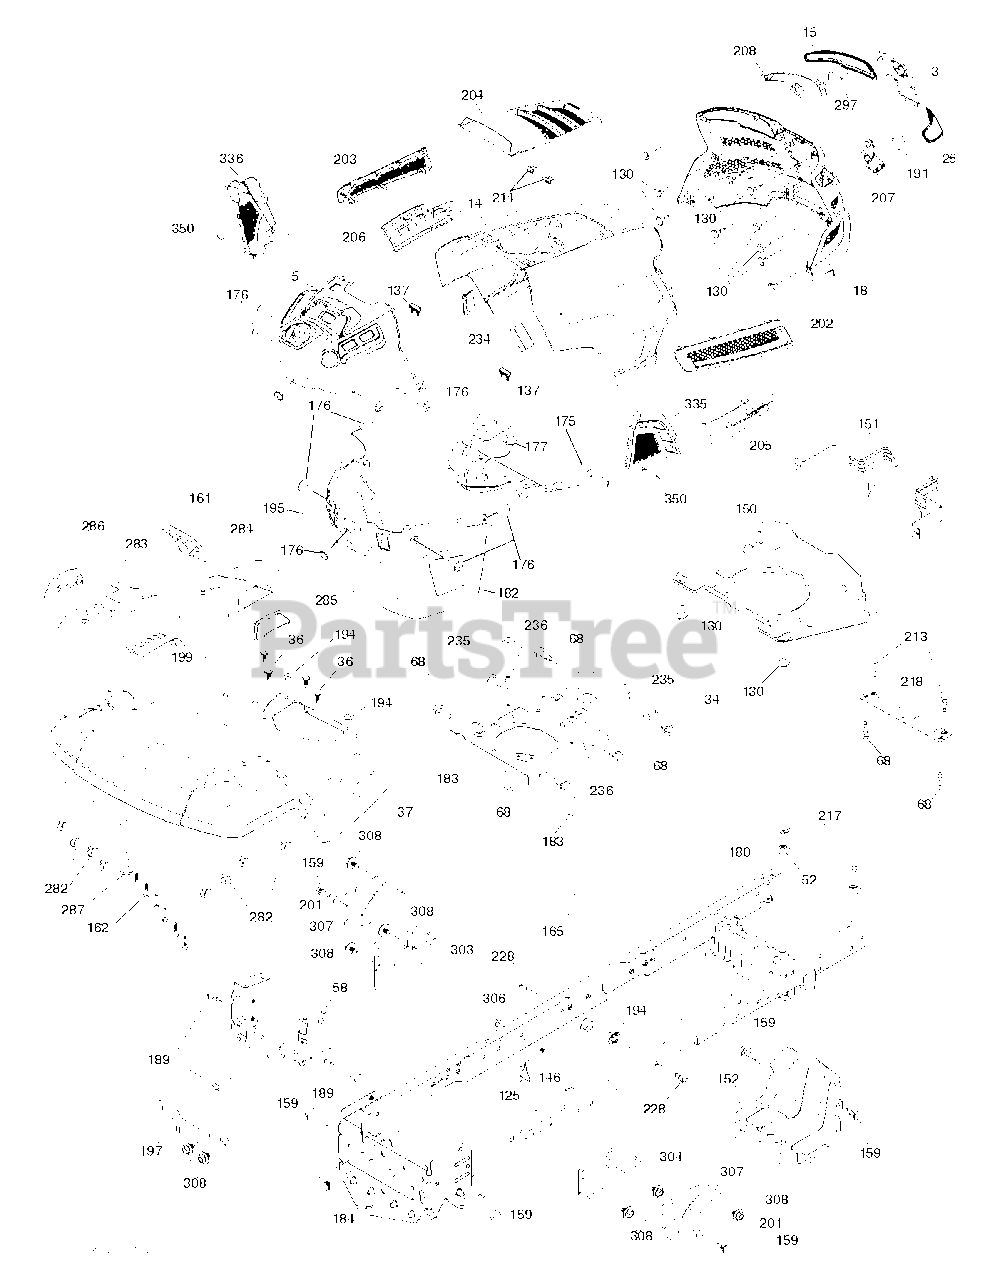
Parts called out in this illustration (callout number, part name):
3	APPLIQUE.SUBASM.GT.HUSQ.II
5	DASH.HUSQ2.SM.E.RS.HR.CHG 498
14	HOOD.ASM.HUSQVARNA.GT.TEX.ORAN
15	LENS.HEADLIGHT.LH.GTII.2011
18	GRILLE.SUBSTRATE.2011.
25	LENS.HEADLIGHT.RH.GTII.2011
34	PLATE.ENGINE.WELDED.CHASSIS
36	SCREW 5/16"
37	FENDER.TLT.FS.W/CPH.W/FW.668
52	LOCKNUT
58	DRAWBAR UPPER 2PC SMALL FENDER
68	SCREW LT
125	CLIP.FUEL.LINE
130	SCREW.#10 X 0.750.BOS
137	BUMPER DASH
146	BOLT.RDHD.SHT.SQNK.3/8-16X5/8
150	AIR.DUCT.GTV.BLACK
151	BRACKET.PIVOT.HOOD.GT.HUSQ.II
152	SHIELD.BROWNING.PNT.GT.V2
159	SCREW, 3/8-16X3/4
161	WINDOW.FUEL.LT.TEX.GREY
162	SCREW.HI-LO.CONSOLE
165	SUPPORT.TANK.REAR.W/TEX
175	PLATE.CROSSMEMBER.HUSQ
176	SCREW.#10-24X5/8.RN.QU
177	BUSHING, STEERING
180	CHASS.WLDMNT.TLT.12GA/2PC.20"
182	DASH LOWER.HUSQ.PRED NO CRUISE
183	BOLT.5/16-18X1-1/4 FULL THD
184	PLUG.DEMO.625
189	SCREW
191	INSERT.REFLECTIVE.RH.HUSQ.GTII
194	NUT LOCK HEX FLANGE 5/16-18
195	PLUG.HOLE.DASH.LOWER.12V.BLK
197	SHIELD.DRWBAR.LT.RTANK.431
199	PLATE.DECK.LIFT.HUSQ.LT
201	WASHER
202	VENT.SIDE.RH.GT.HUSQ.II.
203	VENT.SIDE.LH.GT.HUSQ.II.498
204	VENT.TOP.HUSQ.GT2
205	SIDE.TRIM.RH.GT.HUSQ.II
206	SIDE.TRIM.LH.GT.HUSQ.II.GRAY
207	BEZEL LIGHT.RH.GT.II.MYLAR
208	BEZEL LIGHT.LH.GT.II.MYLAR
213	BOLT
214	CLIP.RETAINER.TINNER.
217	ROD.PIVOT.HOOD
218	X-PIECE.HOOD.STOP.NON/
228	STUD.FASTNER.W/ANTI-ROTATE
234	BUMPER.HOOD.TEX.HUSQVARNA
235	SPACER FENDER
236	NUT.CENTERLOCK.5/16-
282	CLIP.RETAINER.CONSOLE.LT.HUSQ
283	CONSOLE.ASM.LFT.RSF.HUSQ.LT
284	CONCOLE.CNTRL.PDL.HUSQ.LT.498
285	CONSOLE INSERT RH
286	CONSOLE.INSRT.LH.HUSQ.LT.BLACK
287	SCREW 1/4X20
297	INSERT.REFLECTIVE.LH.HUSQ.GTII
303	SHIELD.LOWER.LH/LT/GT/BLK.EDIP
304	SHIELD.RH.LOW.LTGT.NO
306	NUT LOCK FLG 3/8-16 UNC
307	SHIELD.UPPER.LT.GT.ISO
308	BOLT, 5/16-18 X 1 3/4
335	COVER.LOWER.DASH.RH.BLACK
336	COVER-LH.LOWER.DASH.GT2.BLACK
350	CLIP.X-MAS.TREE
